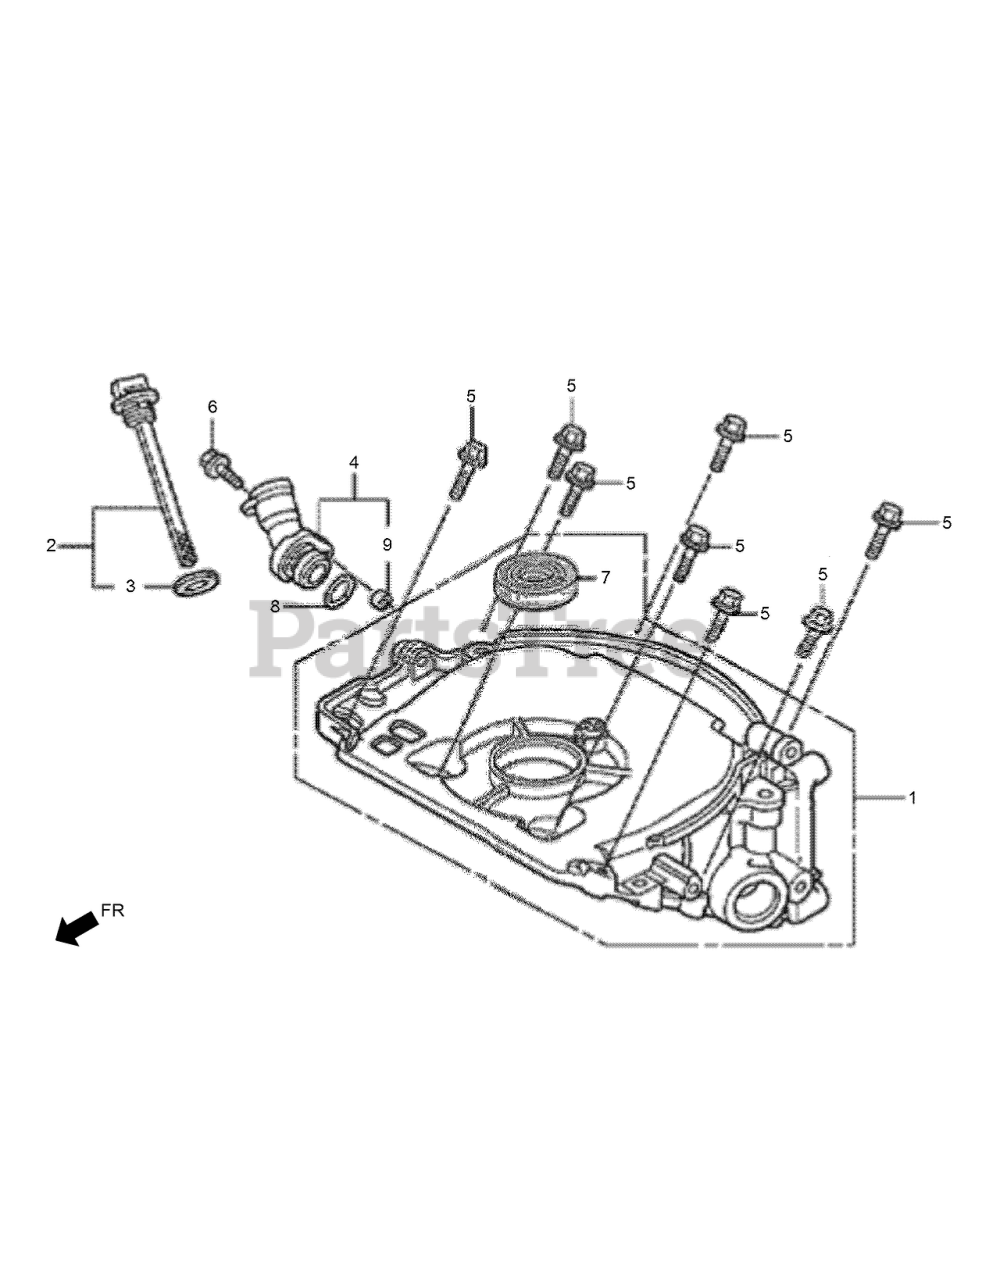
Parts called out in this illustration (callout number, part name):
1	CASE ASM-OIL
2	CAP ASM-OIL FILLER
3	PACKING-OIL FILLER CAP
4	EXTENSION-OIL FILLER
5	BOLT-FLANGE-5X23
6	BOLT-FLANGE-5X14
7	OIL SEAL-17X27X5
8	O-RING-21.2X2.4
9	COLLAR-TOP COVER
